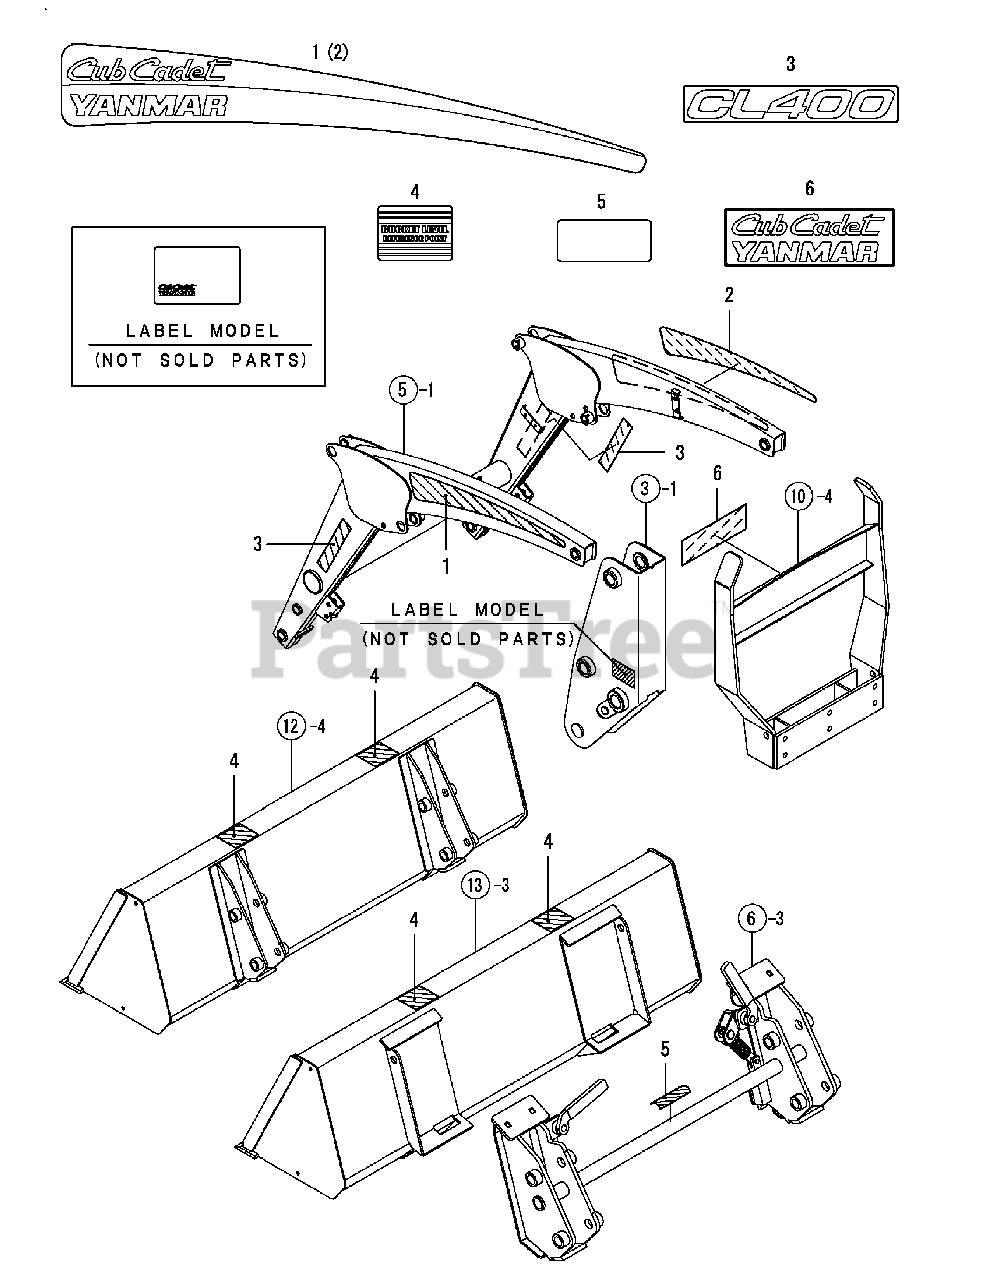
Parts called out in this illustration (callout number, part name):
1	LABEL,LOGO L.H.
2	LABEL,LOGO R.H.
3	LABEL.MODEL CL400
5	LABEL, CAUTION QUICK
6	LABEL, GRILL GAURD
